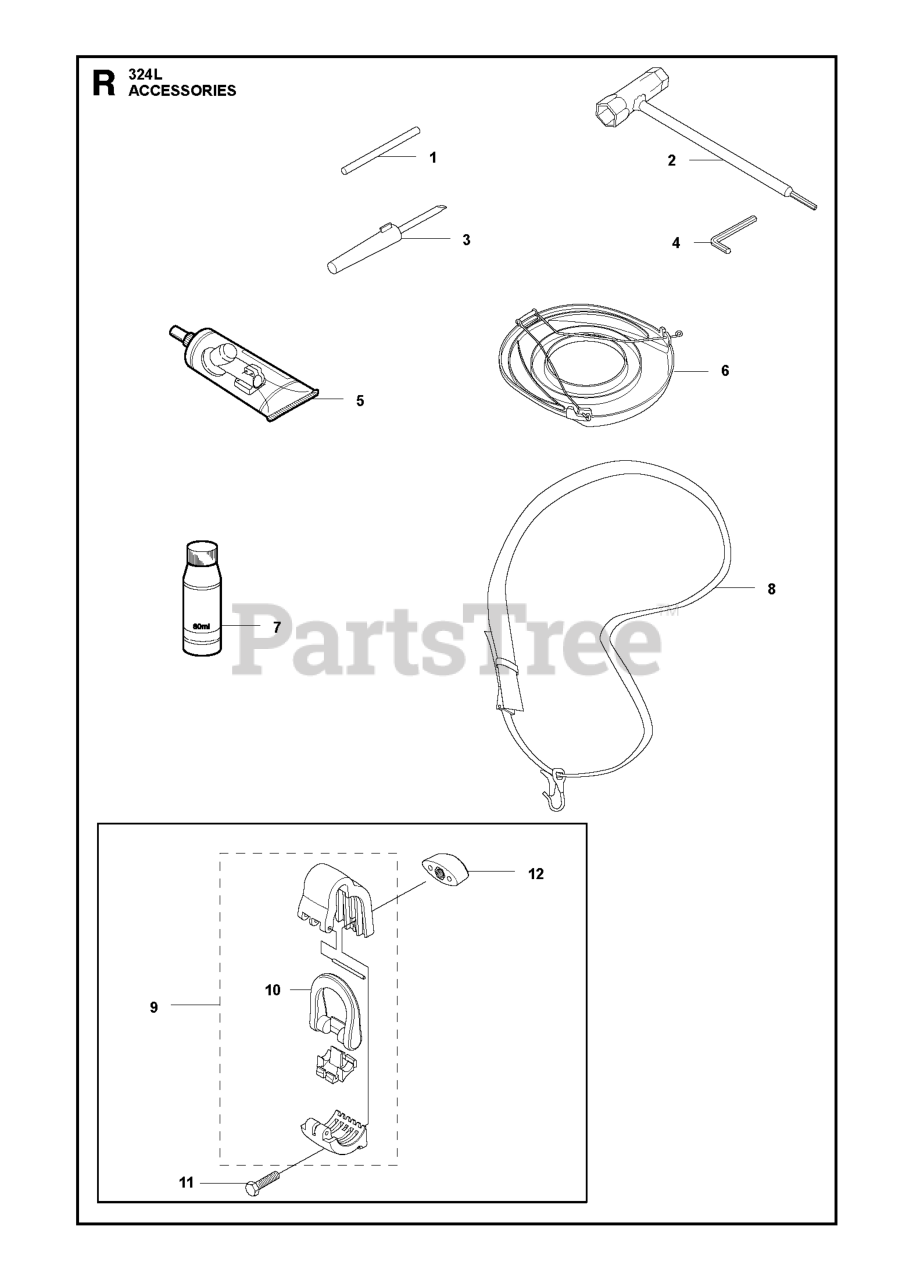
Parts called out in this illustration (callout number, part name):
1	LOCKING PIN
2	RP COMBI TOOL
3	SCREWDRIVER
4	L-KEY WRENCH
5	BEVEL GEAR GREASE
6	BLADE GUARD TRANSPORT
7	Four Stroke Engine Oil (SAE 10W-40) - 1 Bottle per Trimmer
8	Harness-w/o warning
8	Harness - Diagonal with sign
9	HANGING BRACKET
11	SCREW M6S 5X20
